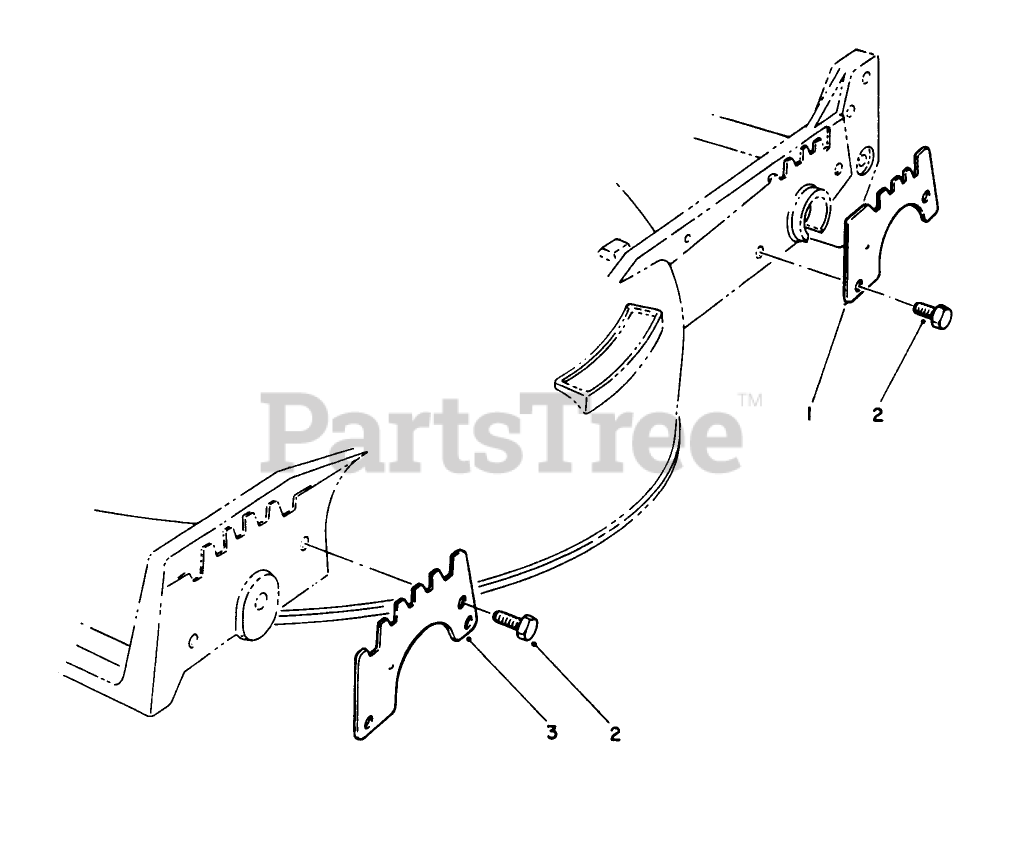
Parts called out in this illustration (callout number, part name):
1	WEAR PLATE,REAR
2	SCREW-HWH
3	WEAR PLATE
